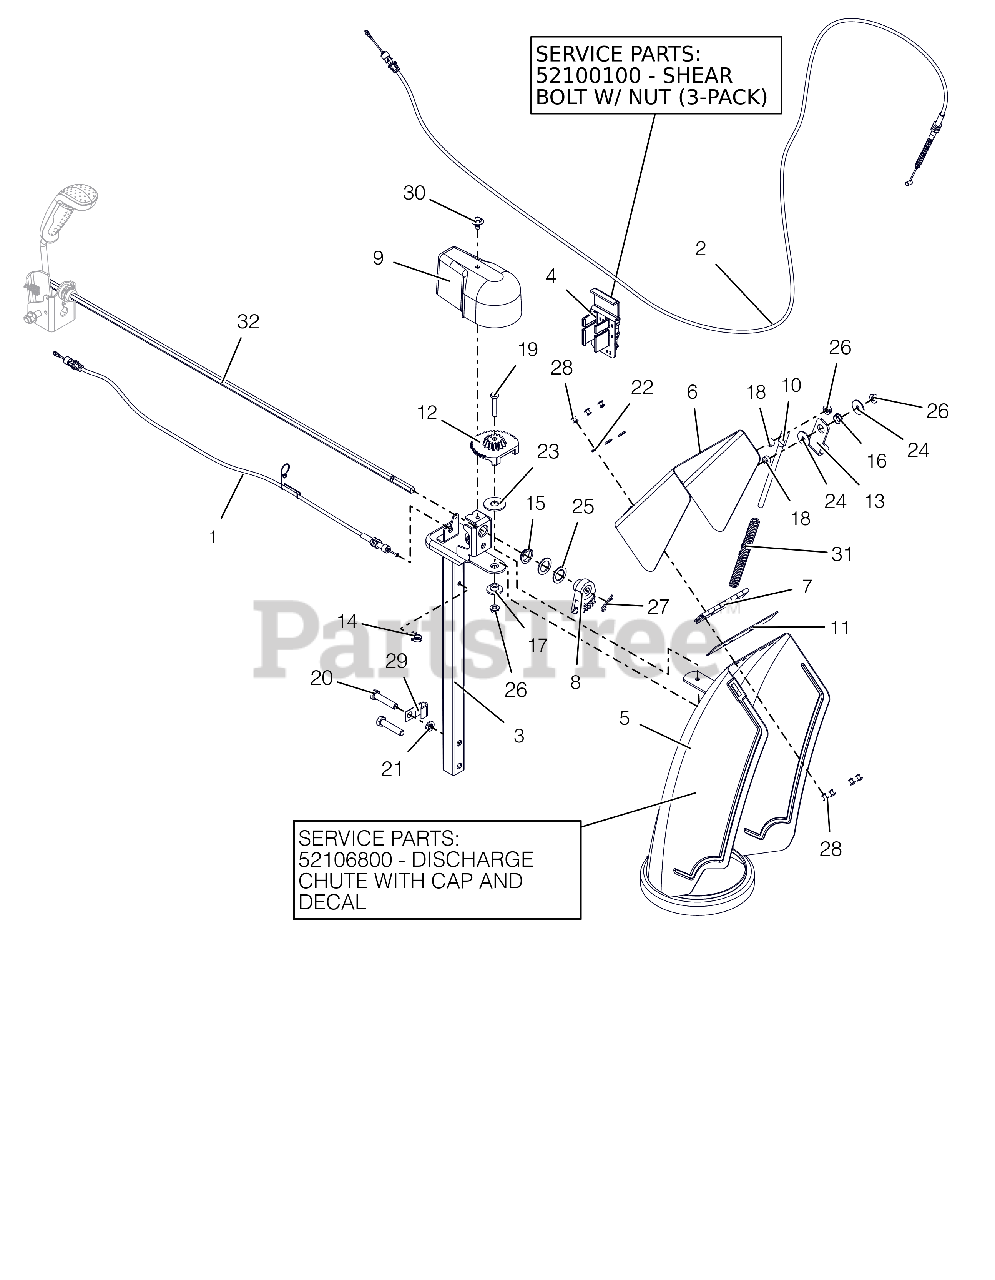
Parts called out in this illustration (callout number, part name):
1	CABLE, CHUTE LOCK, PRO
2	CABLE, DEFLECTOR - DELUXE
3	PEDESTAL, CHUTE - QUICK STICK
4	HOLDER W LARGE SHEAR BOLT /NUT
4	SHEAR BOLT SERVICE ASSEMBLY
5	CHUTE,DISCHARGE,NOTCHED,QT
5	KIT, DISCHARGE CHUTE W/DEF QT2
6	CAP, LARGE REMOTE (W/DECAL)
8	GEAR, CHUTE-ACTUATION
9	COVER, CHUTE GEAR
10	ROD, DEFLECTOR CAP
11	CAP SEAL 5.50
12	GEAR, CHUTE
13	BRACKET, CABLE ANCHOR
14	CLIP, CABLE GUIDE
15	BUSHING, POLYLINER-.75 SNAPIN
16	BUSHING, POLYLINER-.50 SNAPIN
17	BSHG-FLG .265X.477X.375X1.00
18	BSHG-SLV .265X.500X.219
19	@BLT-HEX .25-20X1.50 GR5 YWZC
20	@BLT-HEX .38-16X1.75 GR5 YWZC
21	@WSHR-LK .38X.094 REG YWZC
22	WSHR-FL-STL .196X.500X.06 YZ
23	WSHR-FLT-NYL .515X1.375X.093
24	WSHR-FL-STL .281X1.000X.063
25	WSHR-FL-STL.754X1.125X.062YWZC
26	@NUT-LK-CTR-FLG .25-20 YWZC
27	PIN-HAIR INT .08X.18X1.18 YWZC
28	RVT-POP .187 YZ
29	J-CLAMP
30	SCR-TAP .25-20X.50 LGHWH TR YZ
31	SG-COMP .08X.40X6.50 14#/IN
32	ROD, HEX - CHUTE ROTATION
